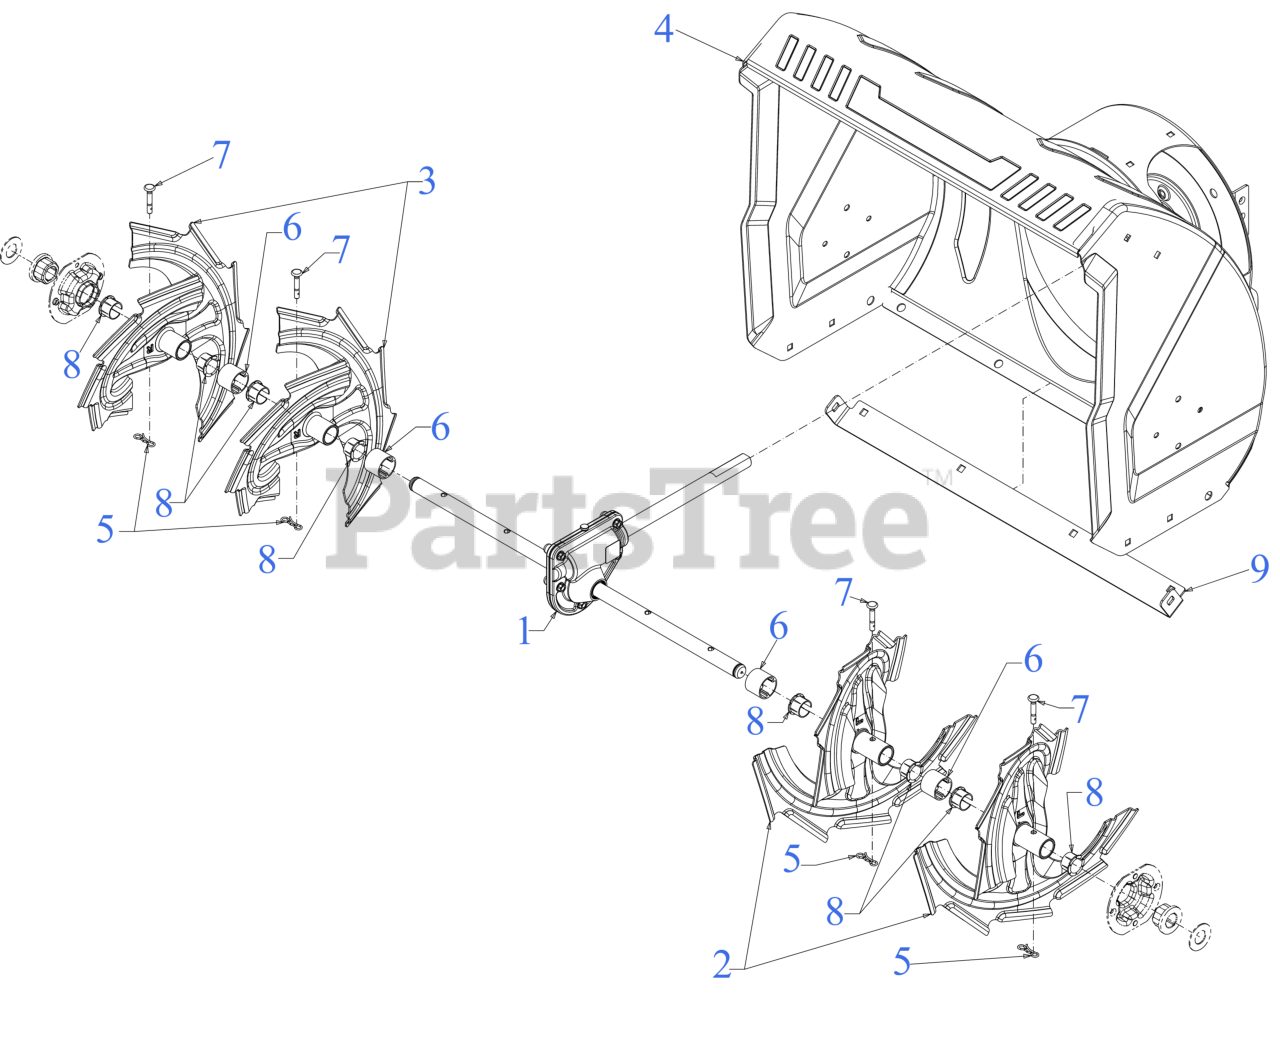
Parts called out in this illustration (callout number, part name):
1	GEARBOX ASSEMBLY 24"
2	10T AUGER SPIRAL (LH)
3	10T AUGER SPIRAL (RH)
4	24" AUGER HOUSING
5	BOW TIE COTTER PIN 1/4-5/16
6	SPACER 1.25OD x .75ID X1.00 LG
7	SHEAR PIN .25 x 1.50 GR2
8	FLANGE BUSHING
9	24" SHAVE PLATE
